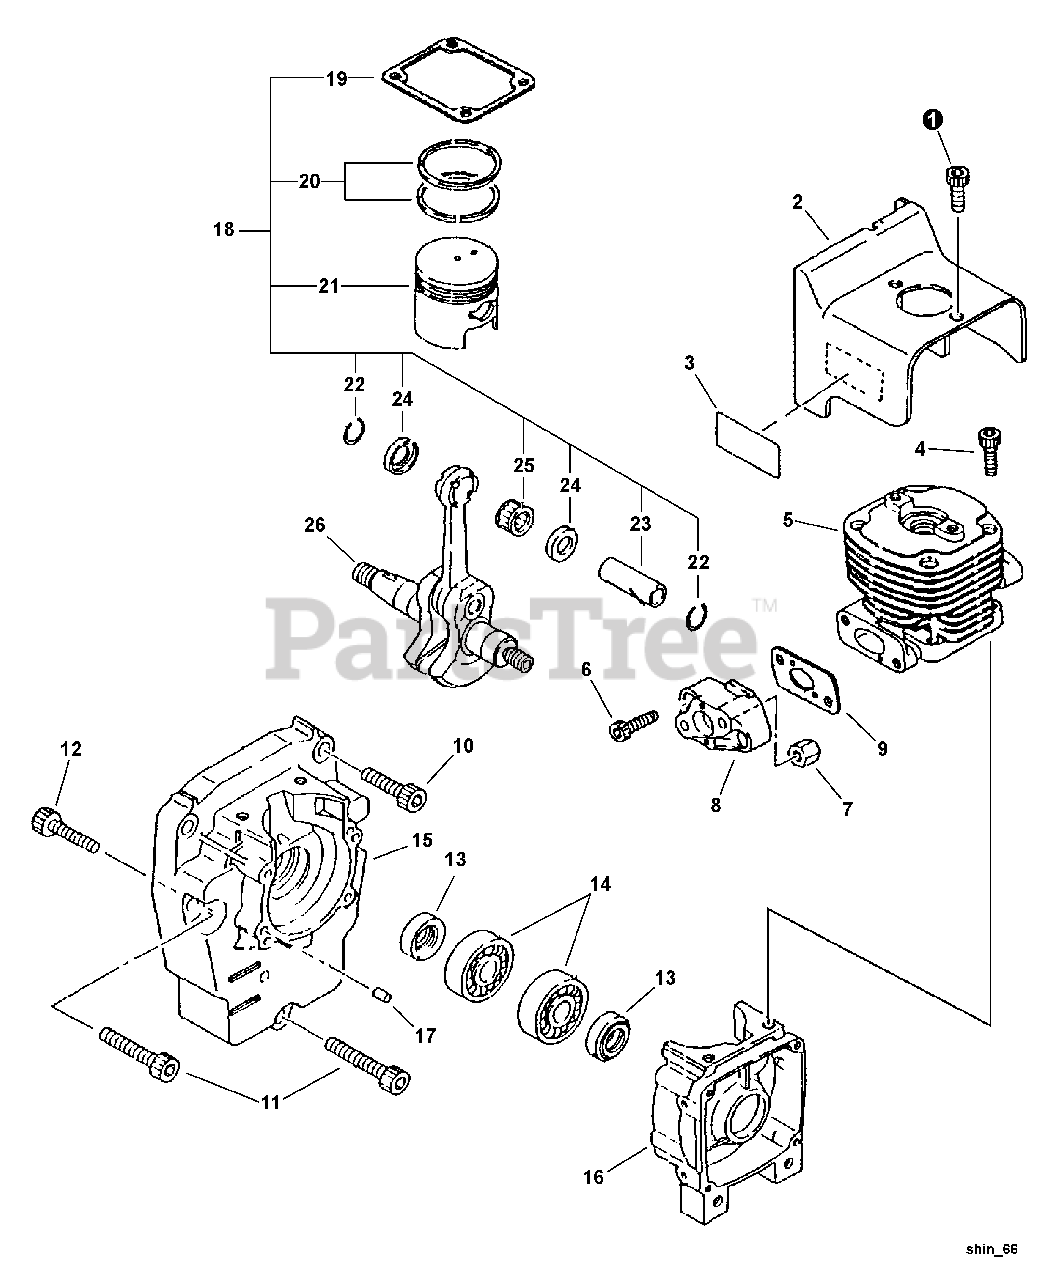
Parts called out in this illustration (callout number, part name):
1	BOLT 5×14
2	COVER, ENGINE
4	SCREW - 5×20
5	CYLINDER
6	SCREW - 5×25
7	NUT M5×6.3
8	INSULATOR
9	GASKET, INTAKE
10	SCREW - 6×30
11	BOLT M6×40
12	BOLT 5×30
13	SEAL, OIL 16
14	BEARING, BALL
15	CRANKCASE - FRONT
16	CRANKCASE S
17	PIN, LOCATING
18	PISTON KIT
19	GASKET, CYLINDER
20	RING, PISTON
21	PISTON
22	RING, RETAINING - 8
23	PIN, PISTON 11
24	WASHER
25	BEARING, NEEDLE 11
26	CRANKSHAFT ASSY
